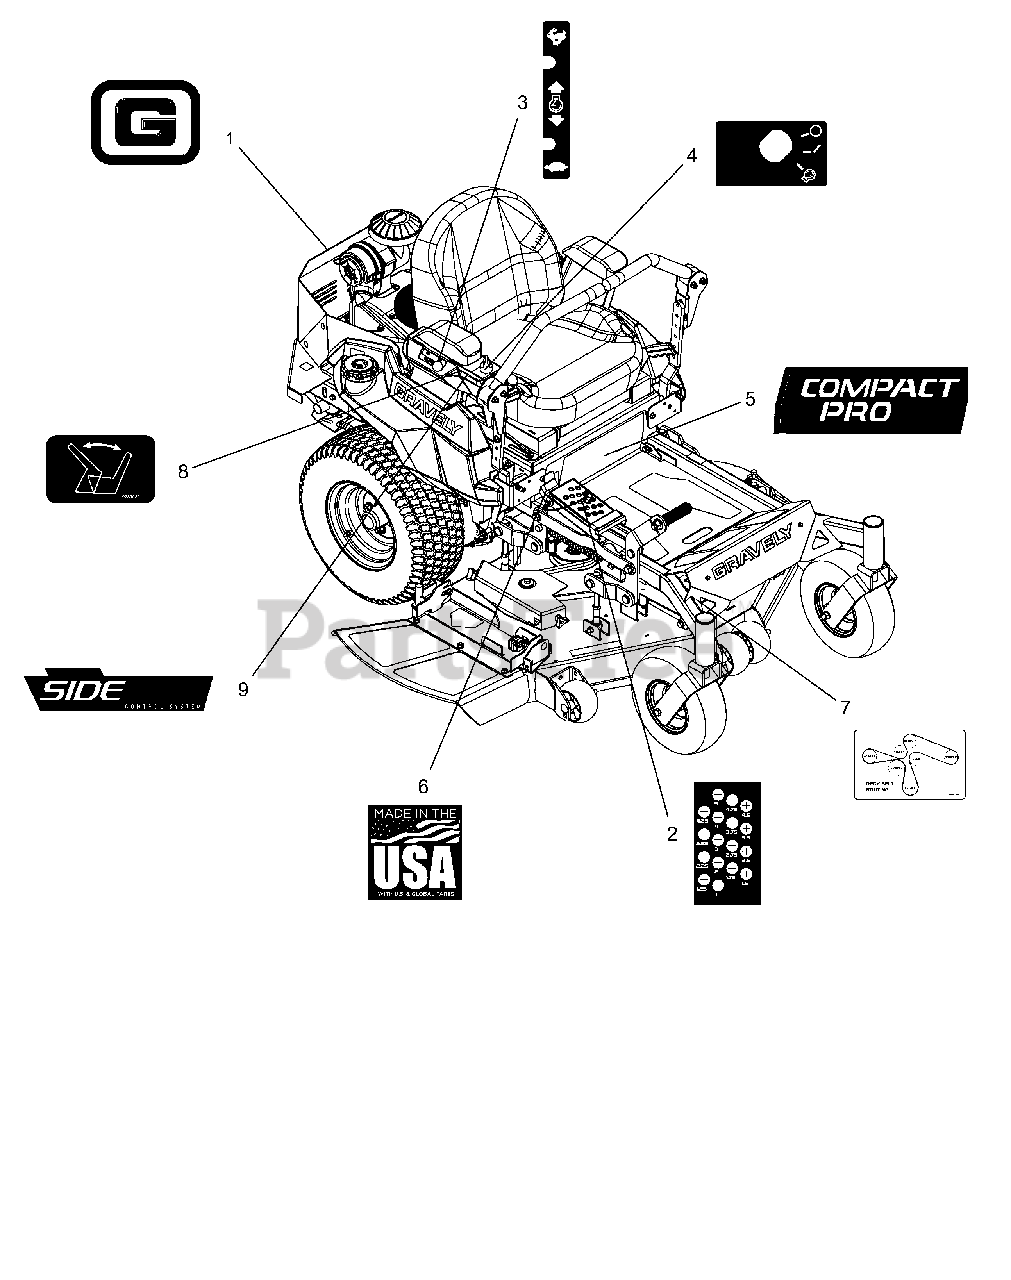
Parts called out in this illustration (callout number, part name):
1	DECAL, GRAVELY BRAND
2	DECAL, COMPACT PRO HOC
3	DECAL, DASH - SPEED
4	DECAL, KEY SWITCH
5	DECAL, COMPACT PRO 44"
6	DECAL, MADE IN USA
7	DECAL, BELT ROUTING
8	DECAL - SEAT RELEASE
9	DECAL, CONTROL COVER
